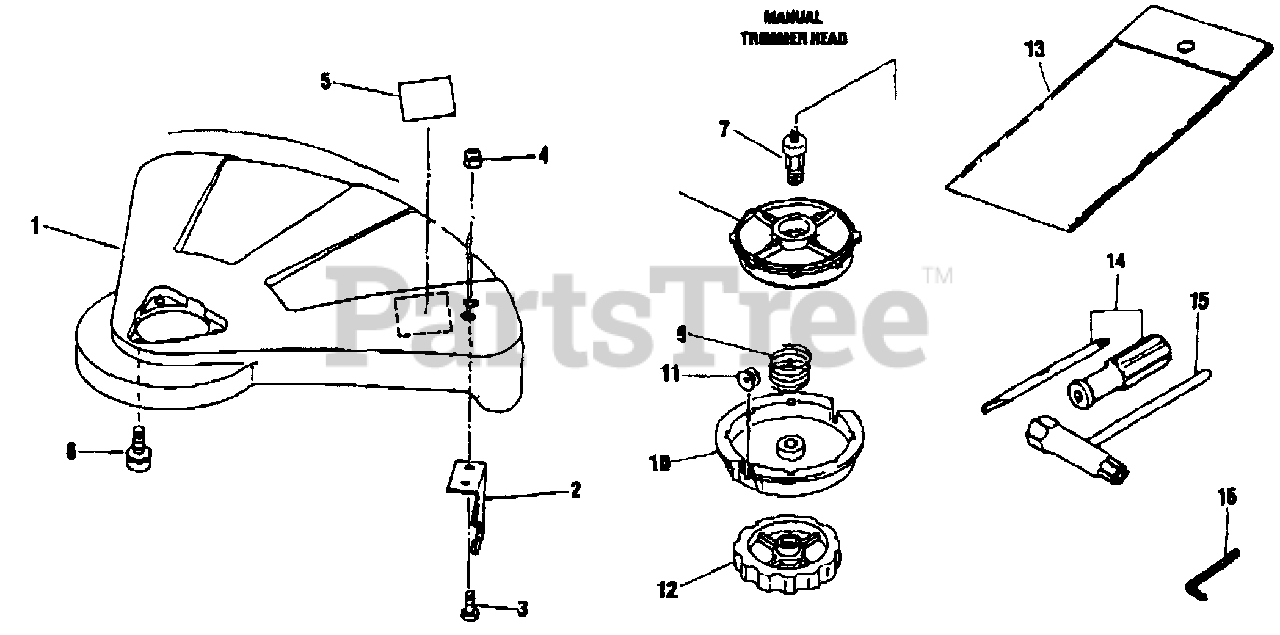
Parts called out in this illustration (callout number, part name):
1	GUARD
2	KNIFE, TRIMMER LINE
4	NUT - NYLON
5	LABEL - CAUTION
6	SCREW - 5X16
7	SHAFT BOLT
9	SPRING
10	SPOOL HOUSING
12	KNOB - LEFT HAND
13	BAG, TOOL
14	SCREWDRIVER
15	T-WRENCH - 13X19mm
16	HEX KEY - 4mm
